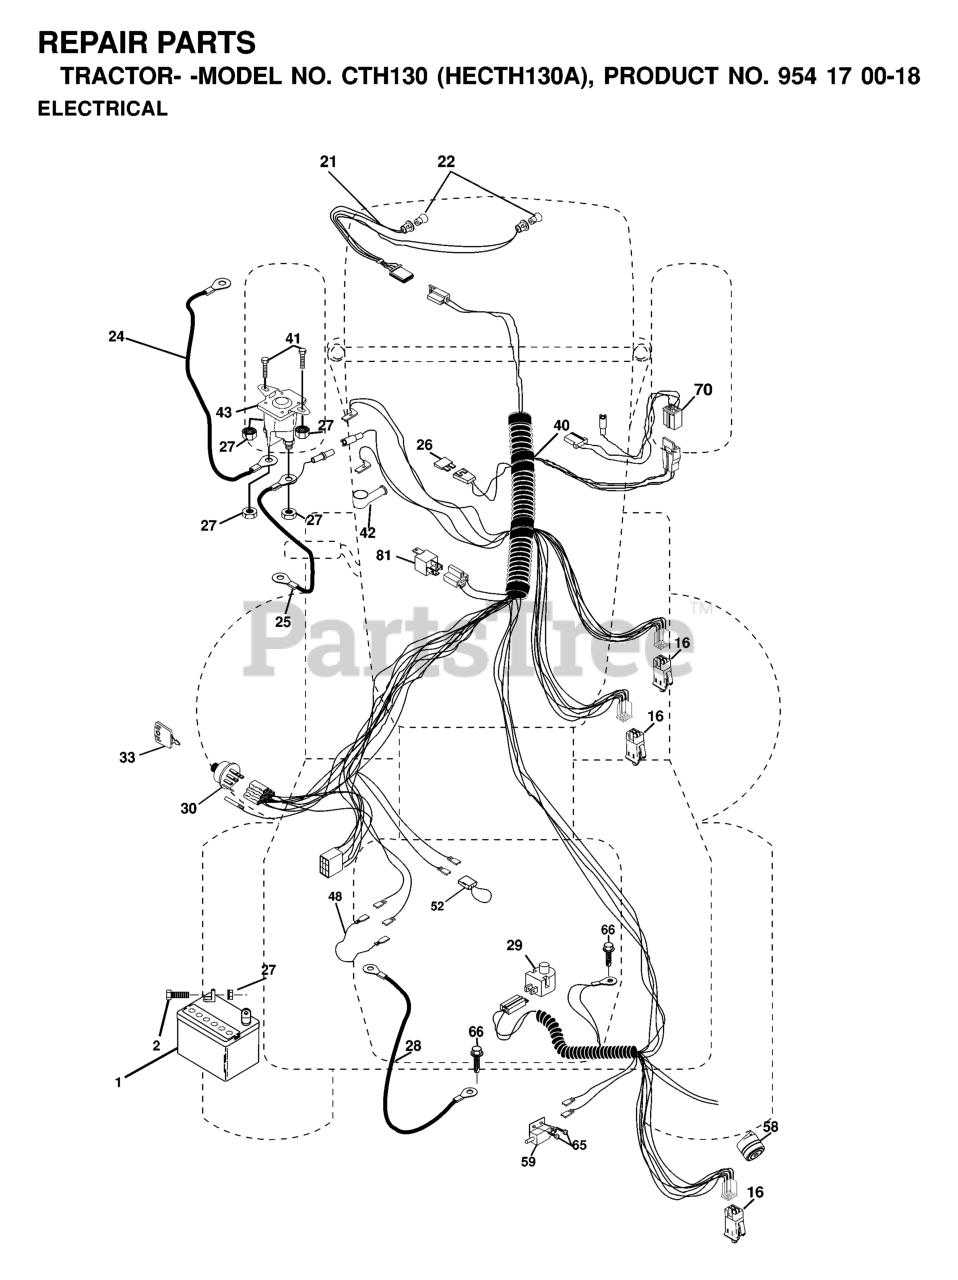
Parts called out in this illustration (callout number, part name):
1	BATTERY 12 VOLT 25 AMP
2	BOLT.HEX.1/4.X.3/4.DICHROMATE
16	SWITCH INTERLOCK
20	NUT
24	BATTERY CABLE GT
25	CABLE BATTERY
26	FUSE 15 AMP
27	NUT
28	CABLE GROUND
29	PLUNGER SWITCH (COLOR:OLIVE)
30	SWITCH IGN
33	KEY MLD GEN DELTA
40	Harness Ign Crd Noram
41	BOLT
42	TERMINAL COVER
43	SOLINOID
48	ADAPTER.AMMETER
52	WIRE PROTECTION LOOP
58	BUZZER
65	Screw, Hex Wsh. Tap #10-16 x 1/2
70	ENGINE HARNESS
81	RELAY.ASSY.T
